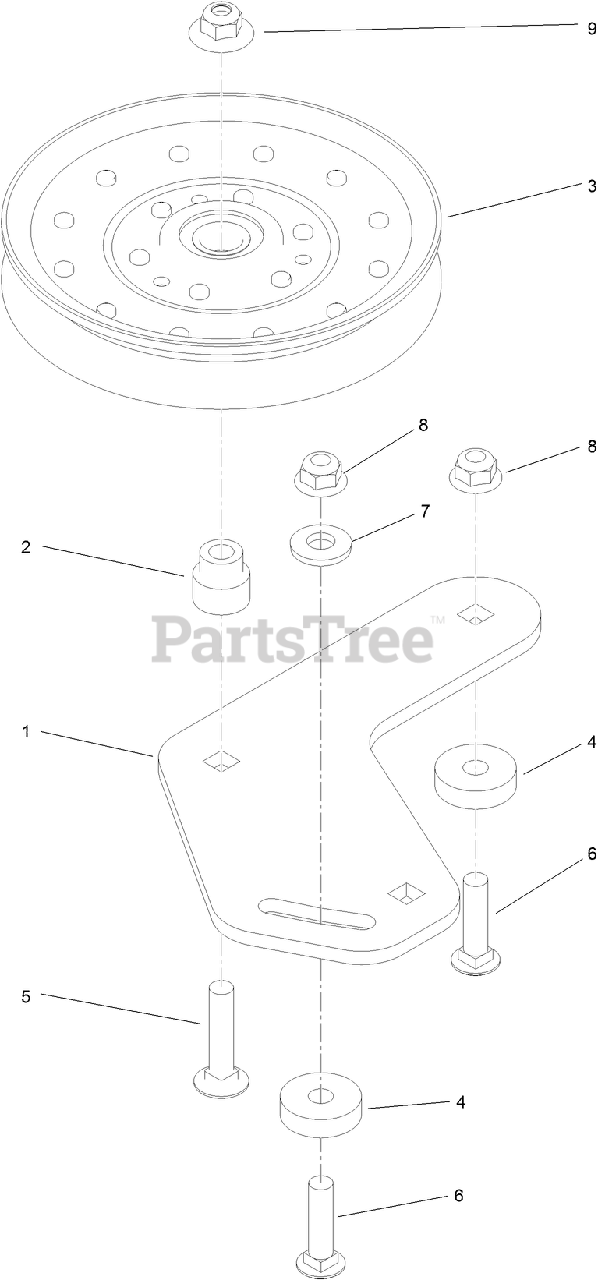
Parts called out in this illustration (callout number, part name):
1	ARM-IDLER, LH
2	BUSHING-IDLER
3	IDLER-PULLEY, FLAT
4	Spacer
5	SCREW-CARR
6	SCREW-CARR
7	WASHER-BELLEVILLE
8	NUT-HF, NI
9	NUT-FLANGE, NI
